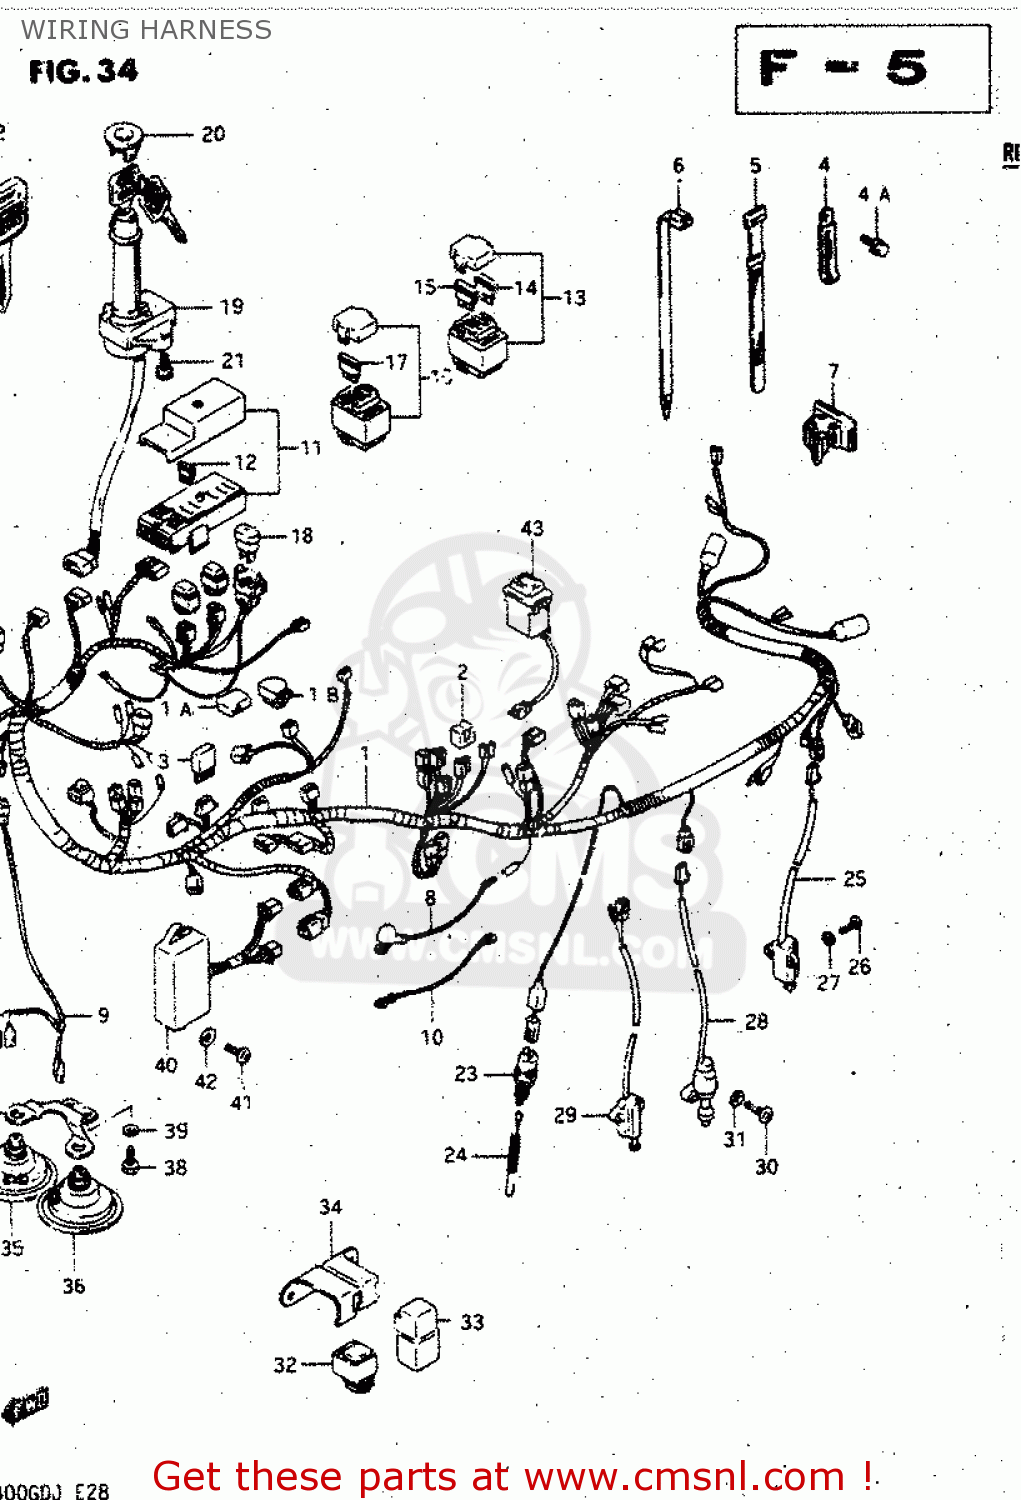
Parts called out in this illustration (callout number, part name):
1	HARNESS,WIRING
1A	CAP,BATTERY PLUS TERMINAL
1B	CAP,STARTER RELAY TERMINAL
2	RECTIFIER ASSY
3	DIODE(STANLEY DE8804)
4	CLAMP
4A	BOLT 8X12
5	CLAMP(L:120)
6	CLAMP(L:165)
7	CLAMP
8	WIRE,WATER TEMPERATURE GAUGE
9	WIRE
10	WIRE
11	BOX ASSEMBLY,FUSE
12	FUSE(10A)
13	BOX ASSEMBLY,FUSE
14	FUSE(3A)
15	FUSE(5A)
16	BOX ASSEMBLY,FUSE
17	FUSE(10A)
18	BREAKER ASSY,CIRCUT
19	LOCK ASSEMBLY,STEERING
20	CAP,IGNITION SWITCH
21	BOLT
22	KEY,BLANK
23	SWITCH ASSY,STOP LAMP
24	SPRING
25	SWITCH ASSEMBLY,SIDE STAND
26	SCREW
27	WASHER,LOCK
28	SWITCH ASSEMBLY,SIDE STAND
29	SWITCH ASSEMBLY,SIDE STAND
30	SCREW
31	WASHER,LOCK
32	RELAY ASSY
33	RELAY ASSEMBLY
34	BRACKET
35	HORN,HIGH TONE
36	HORN,LOW TONE
37	BRACKET,HORN
38	BOLT
39	WASHER,LOCK
40	RELAY ASSEMBLY,LAMP OUTAGE
41	SCREW
42	WASHER, LOWER
43	SWITCH ASSEMBLY,AUTO LEVEL
